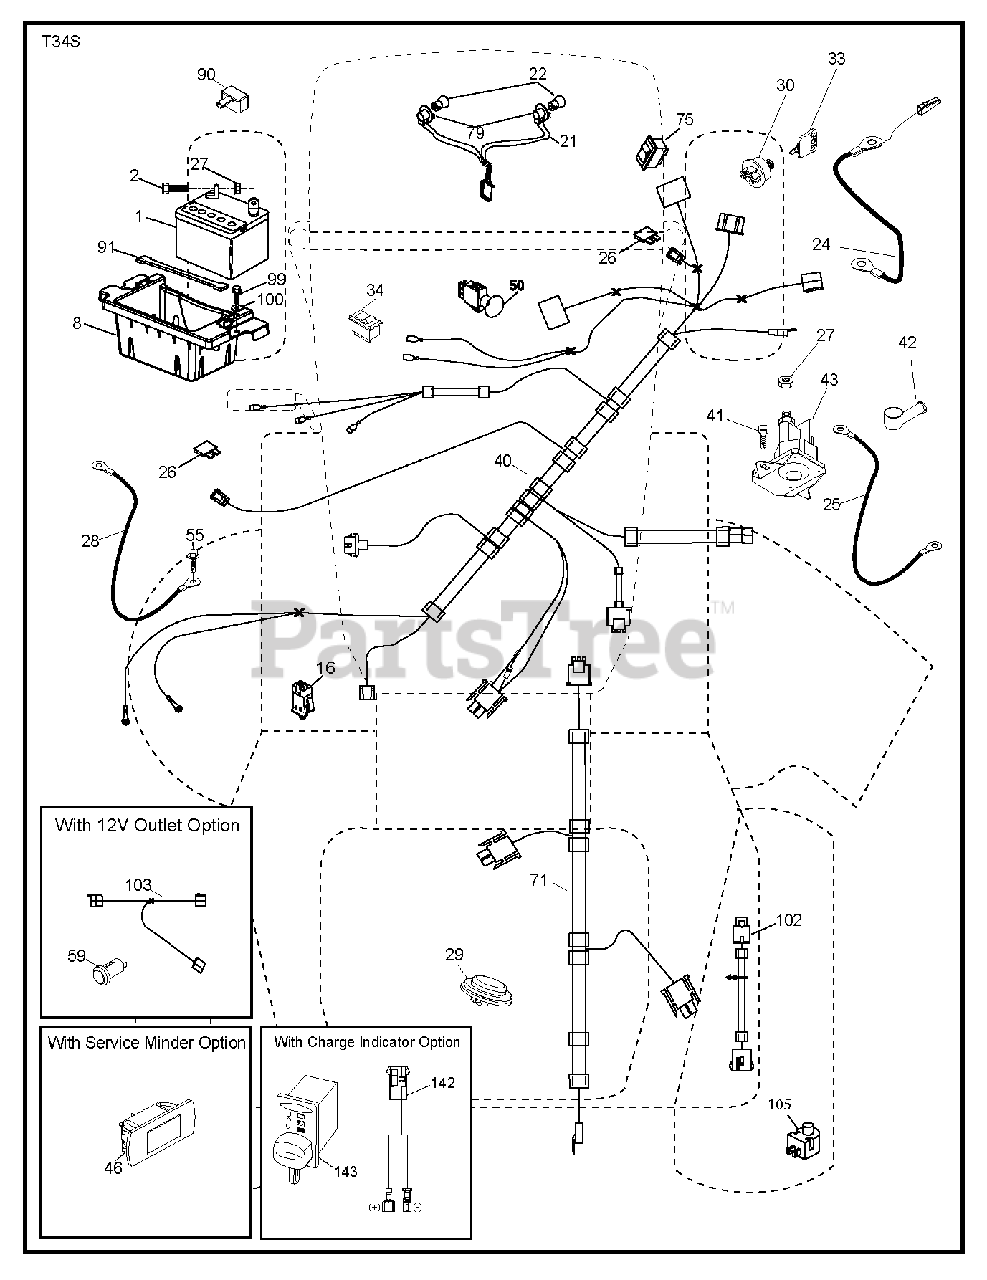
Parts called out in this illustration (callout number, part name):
1	Battery, Dry 30 Amp
2	BOLT.HEX.1/4.X.3/4.DICHROMATE
8	BOX.BATTERY.MOUNT.FRONT.LT
16	SWITCH INTERLOOK PUSH-IN
21	HARNESS.LIGHT W/4152J BULBS
24	CABLE.BATT.POS.WIRE.TG.DA SOL
25	CABLE.STARTER.6G.BL/RED.17.5
26	FUSE 20AMP
27	NUT
28	CABLE GROUND 6 GA 21" 90T BLK
29	SWITCH.SEAT.DELTA.OPC.
30	SWITCH.IGN.DELTA.W.LGH.ROS
33	KEY.CHAIN.BLISTER.PACK.GEN.USA
40	HARNESS.IGN.DASH.HUSQ/PRED.
41	SCREW
42	TERMINAL COVER
43	SOLENOID.W/BRASS.PLUNGER
46	RP GUAGE.SRVCMNDR.HRMTR.
50	RB PTO.SWITCH.8 TERMINAL.BLACK
55	SCREW 5/16"
59	OUTLET.12-VOLT
71	HARNESS.IGN.CHASSIS.TEX.DCKLOC
75	SWITCH.ON/OFF.(DIFF.LOCK)
79	BULB HOLDER ASM.
90	COVER.TERMINAL.BATTERY
91	STRAP.BATTERY.MOUNT.FRONT(2 2)
99	SCREW HEXWSHR 1/4-20X3/4
102	HARNESS PIGTAIL PCH TEX ROS
103	HARNESS PIGTAIL 12V OUTLET
105	REVERSE SWITCH
142	CHARGE.PORT.PIGTAIL HARNESS
143	CHARGE.PORT
